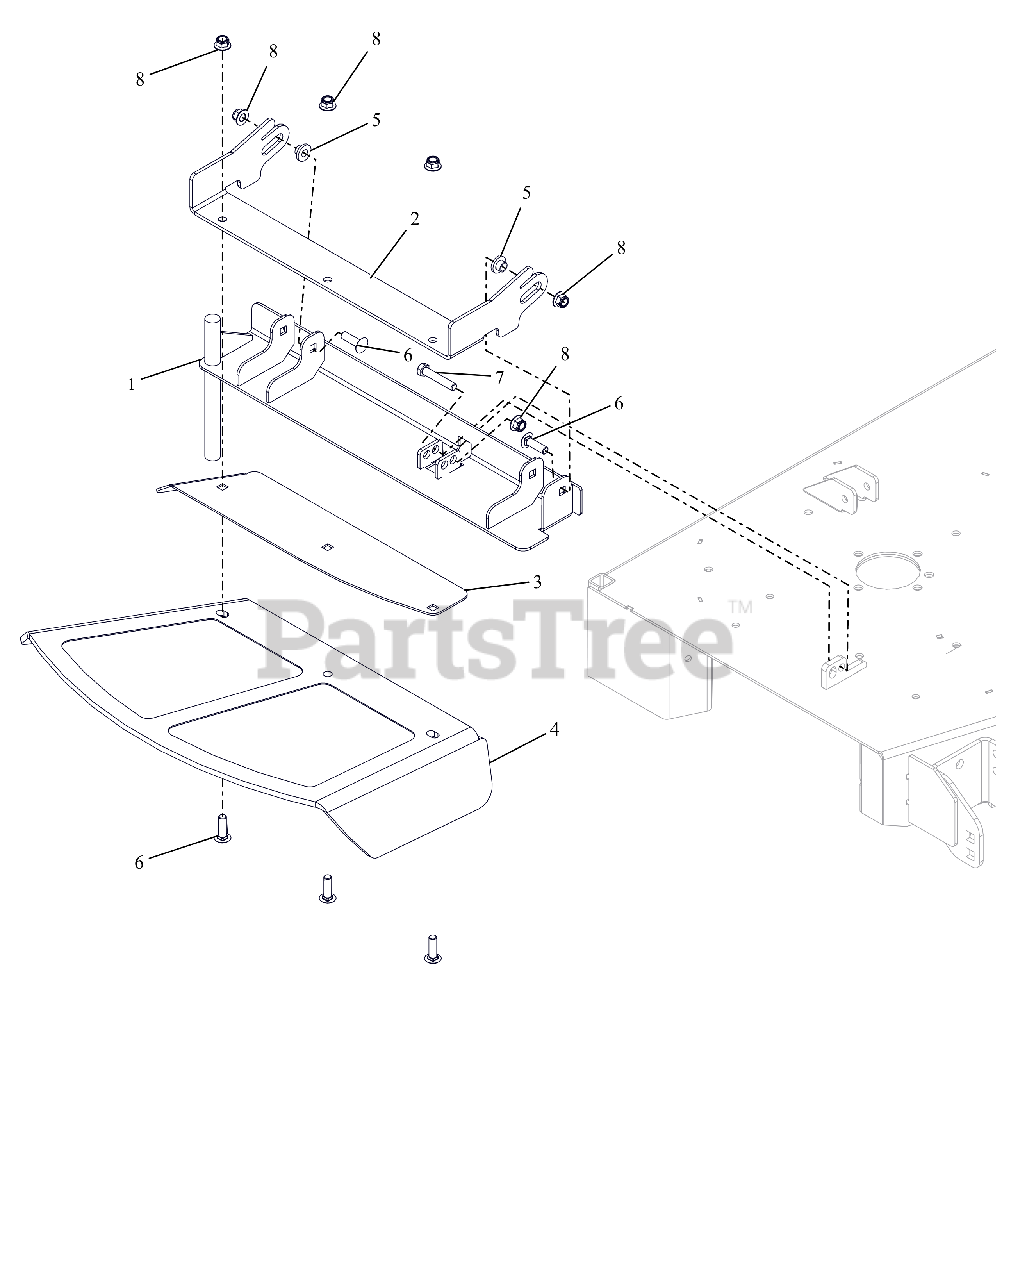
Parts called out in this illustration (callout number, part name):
1	44-60 DISCH CHT WMT ORG W/SAFE
2	48-60" CHUTE MTG BRKT -ORG
3	48-60 DISCH CHUTE CLMP PLT-ORG
4	CHUTE,48-60" FRMD RUBBER DISCH
5	BSHG-FLG .385X.500X.875X.406
6	@BLT-RHDSSQNK .38-16X1.25 G5YZ
7	@BLT-HEX .38-16X2.00 GR5 YWZC
8	@NUT-LK-NYL-FLG .38-16 YWZC
